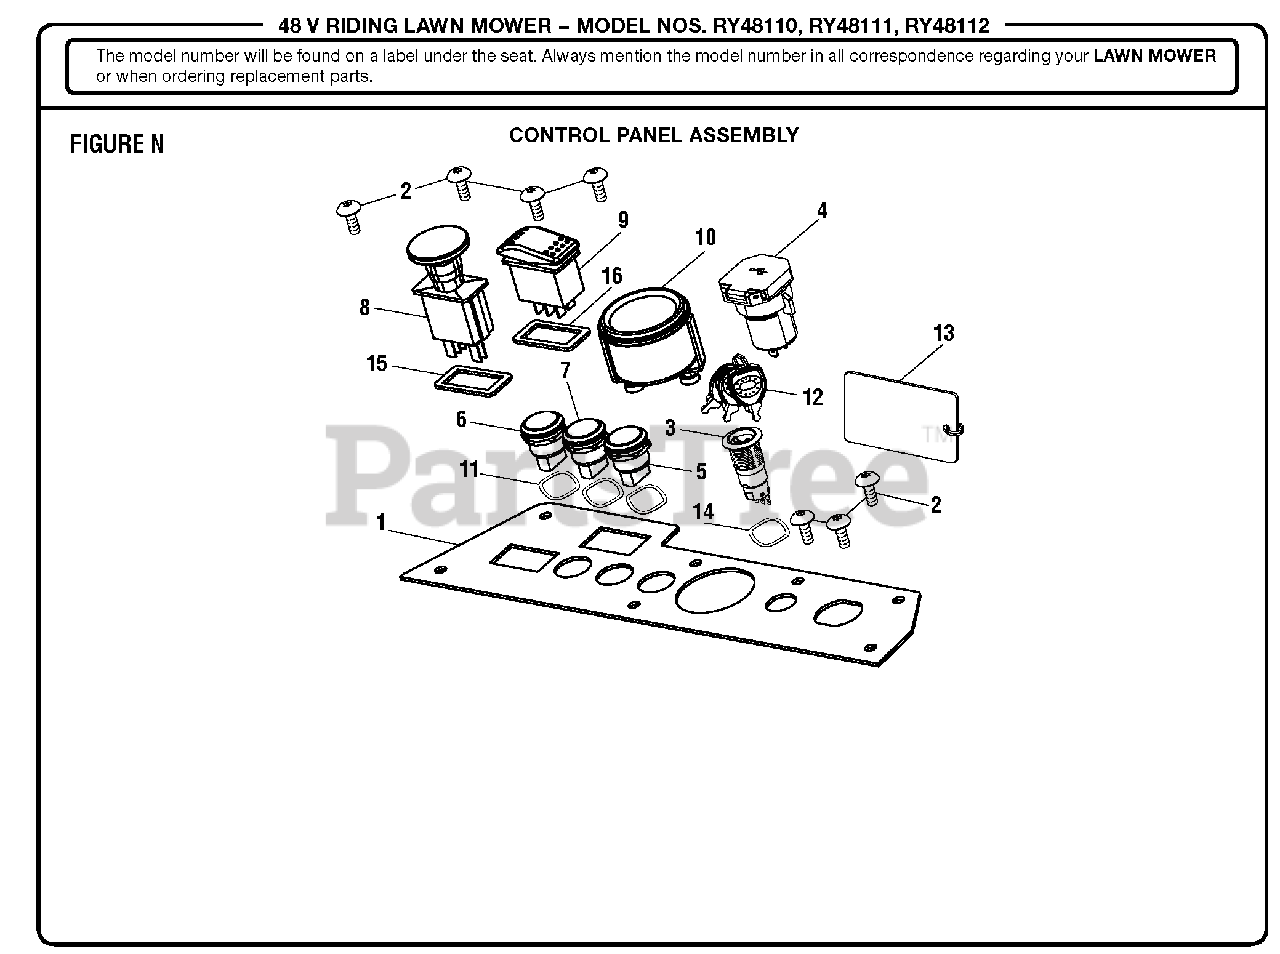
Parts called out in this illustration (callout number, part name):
1	Face Plate
2	Screw (M6 x 10 mm, Soc. Button Hd.)
3	Switch Key Module
4	USB Module
5	Light Switch
6	Cruise Button
7	Reverse Mow Operation Button
8	Power Take Off Button (PTO)
9	Toggle Switch
10	Gauge Module
11	Wavy Washer
13	Warning Tag
14	Wavy Washer
15	Rubber Gasket
